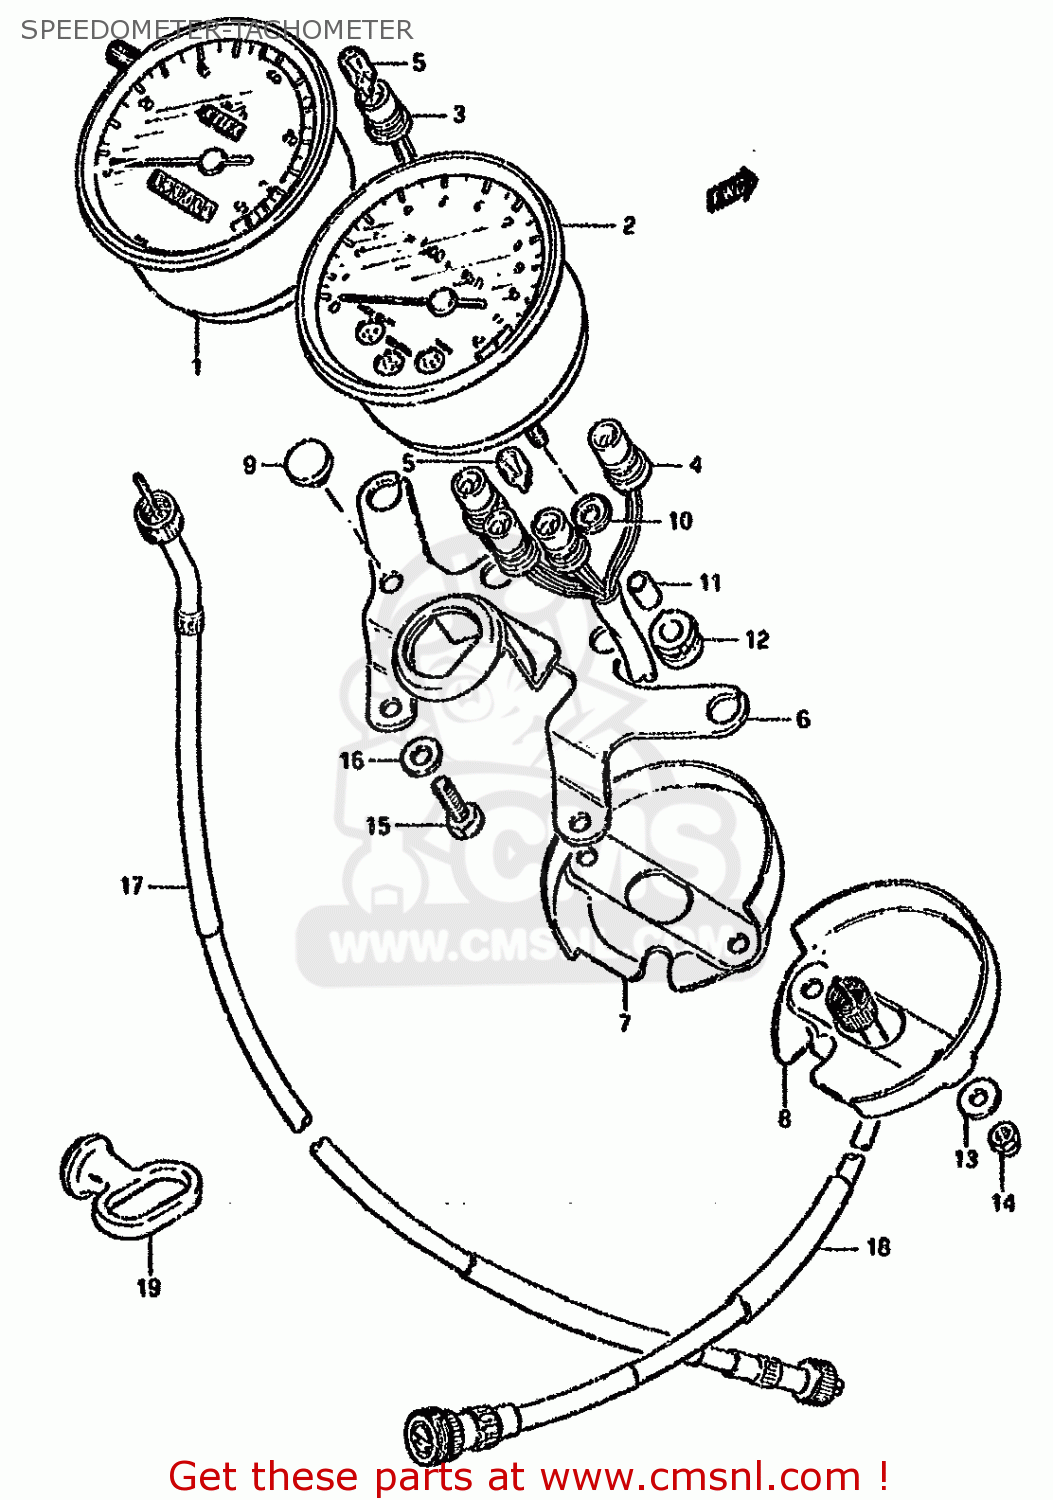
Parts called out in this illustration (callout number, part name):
1	SPEEDOMETER(KILO)
2	TACHOMETER
3	SOCKET,SPEEDOMETER
4	SOCKET,TACHOMETER
5	BULB(12V3.4W,T10,BF175-01450A)
6	BRACKET,METER
7	UNDER COVER,SPEEDOMETER
8	UNDER COVER,TACHOMETER
9	CUSHION,METER
10	WASHER
11	SPACER,SPEEDOMETER
12	CUSHION,METER
13	WASHER,METER
14	NUT
15	BOLT
16	WASHER
17	CABLE ASSY,SPEEDOMETER
18	CABLE ASSY,TACHOMETER
19	GUIDE,CABLE
